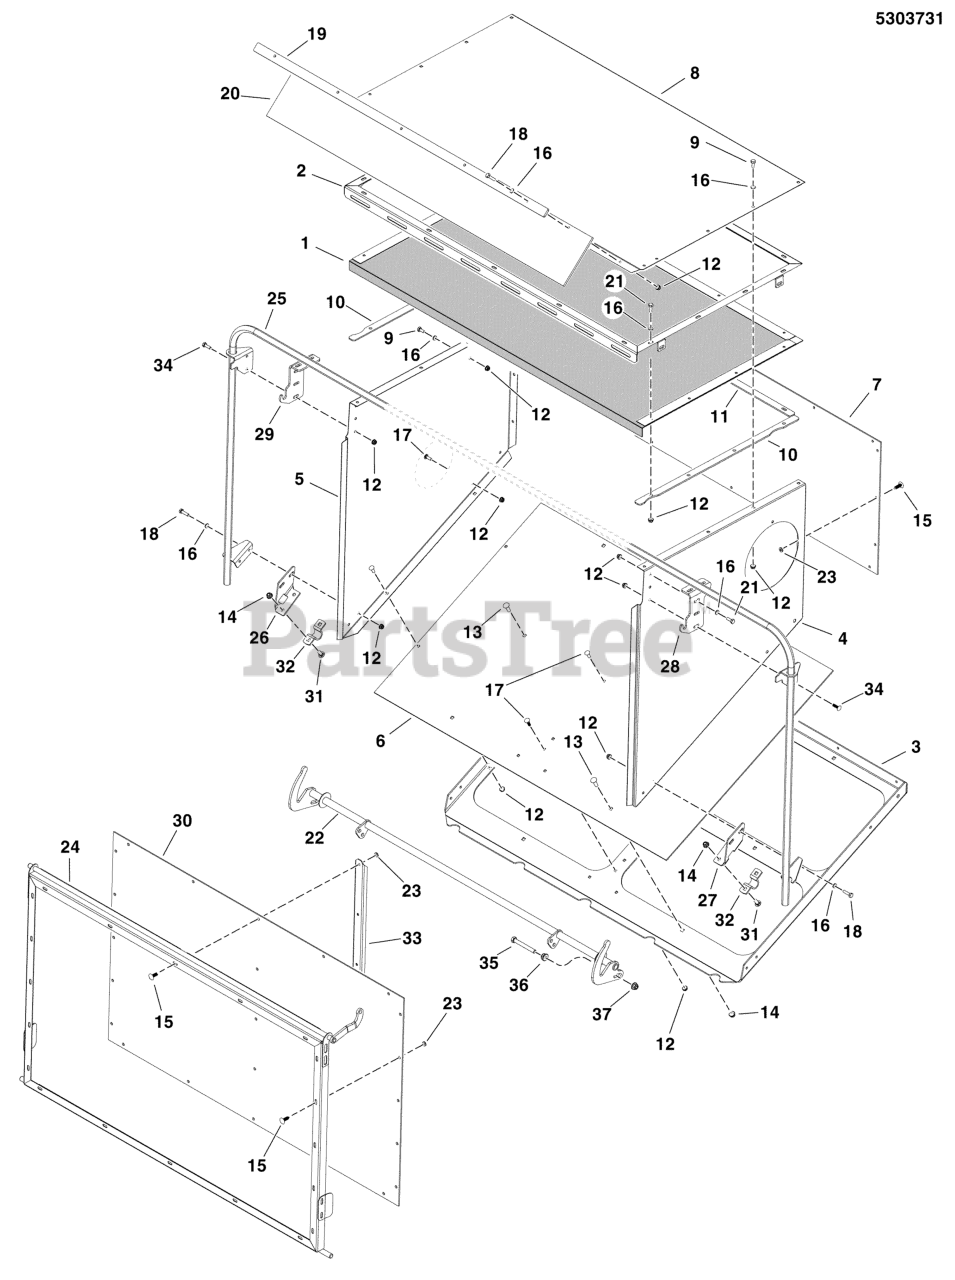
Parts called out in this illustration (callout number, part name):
1	SCREEN, ASM, 12FT HOPPER
2	WELD, SCREEN FRAME, 12FT HOPPER - BLK
3	WELD, SUBFRAME, 12FT HOPPER - BLK
4	PANEL, RIGHT, 14FT HOPPER - BLK
5	PANEL, LEFT, 14FT HOPPER
6	PANEL, BOTTOM, 12FT HOPPER
7	PANEL, FRONT, 12FT HOPPER
8	PANEL, TOP, 12FT HOPPER - BLK
9	HHCS, 1/4-20 X 0.625, GR5, ZINC/CLEAR
10	STRIP, SHORT CLAMP, 12FT HOPPER - BLK
11	STRIP, LONG CLAMP, 12FT SCREEN - BLK
12	NUT, 1/4-20 Hex Nylock Flange
13	BOLT, 5/16-18 X 1, CARRIAGE, GD5, CZ
14	NUT, 5/16-18 HEX NYLOCK FLANGE NUT
15	PUSH RIVET (TREE TYPE), BLACK
16	WASHER, 1/4 SAE
17	BOLT,1/4-20X0.750,GR5,STD NECK,SQ,ZC/CL
18	BOLT, 1/4-20 X 1" GD5 CZ
19	BAR, DEFLECTOR, 12FT HOPPER - BLK
20	DEFLECTOR, RUBBER, 12FT HOPPER
21	BOLT, 1/4"-20 X 3/4" GD5 YZ
22	WELD, LATCH ASSY, 12FT HOPPER - BLK
23	WASHER, #12 SAE FLAT, .25X.531X.051, CZ
24	WELD, GATE FRAME, 12FT HOPPER - BLK
25	WELD, ARCH ASSEMBLY, 12FT HOPPER - BLK
26	BRACKET, GATE LATCH, LEFT - BLK
27	BRACKET, GATE LATCH, RIGHT - BLK
28	PLATE, HINGE RIGHT, HOPPER - BLK
29	PLATE, HINGE LEFT, HOPPER - BLK
30	PANEL, GATE, 12FT HOPPER
31	BOLT, 5/16-18 X 3/4, CARRIAGE, GD5, CZ
32	STRAP, ROCKER SHAFT
33	BRACKET, RIB, HOPPER - BLK
34	RHSSNB, 1/4C X1 GR5 Z
35	BOLT, 3/8-16 X 3" GD5 CZ
36	NUT, 3/8-16 Hex Large Serrated Flange
37	NUT, 3/8 - 16 HEX NYLOCK FLANGE
